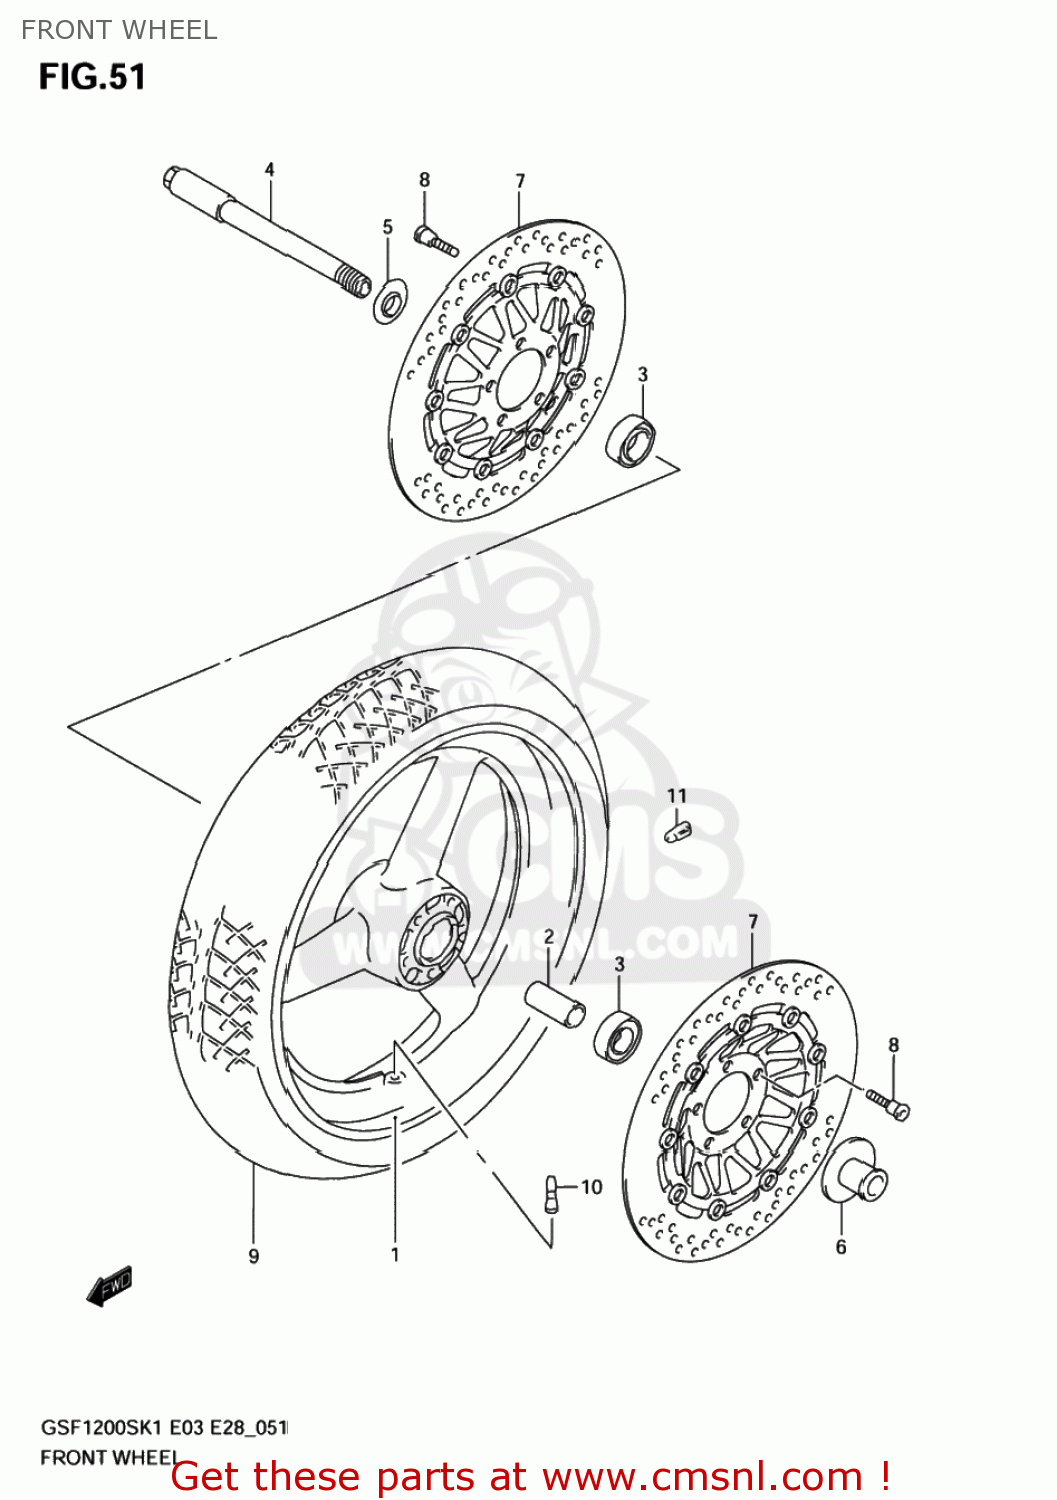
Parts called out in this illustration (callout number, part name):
1	WHEEL,FRONT
2	SPACER(20.8X27.2X74)
3	BEARING
4	AXLE,FR
5	SPACER,FR HUB BEARING,R
6	SPACER,FR AXLE,L
7	DISC,FR BRAKE
8	BOLT 8X33
9	(MICHELIN) PURCHASE LOCALLY
10	VALVE ASSY,WHEEL RIM(TR412)
11	BALANCER,WHEEL(10G)
